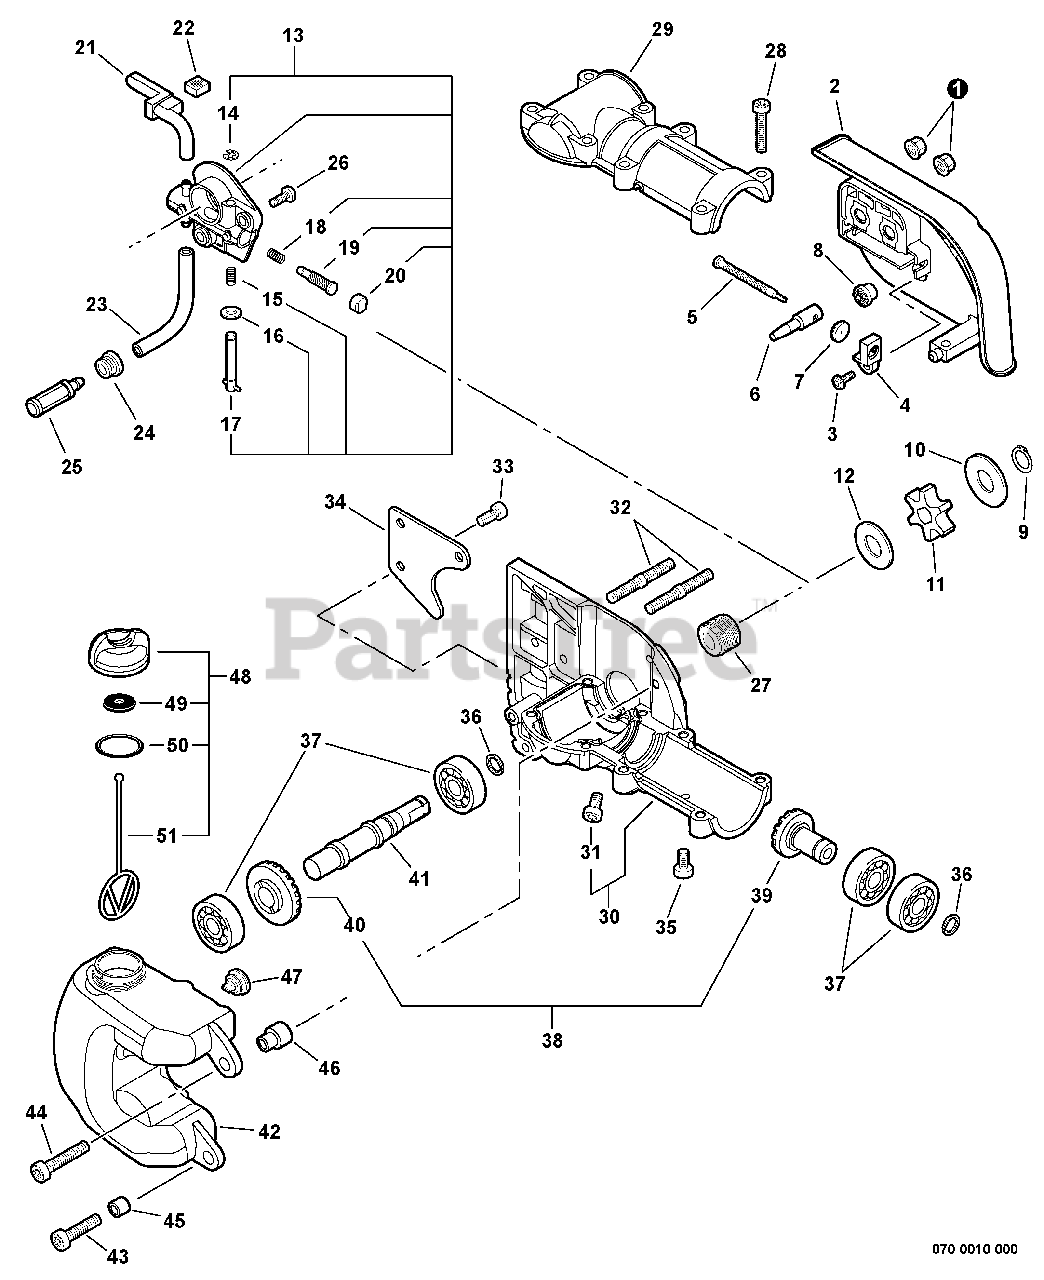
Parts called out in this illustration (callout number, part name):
1	NUT, FLANGE M6
2	GUARD, SPROCKET
3	SCREW 4
4	COLLAR 8
6	TENSIONER, CHAIN
7	GEAR - 14 TOOTH
8	GEAR - 14 TOOTH
9	RING, SNAP
10	WASHER 10
11	SPROCKET, DRIVE
12	WASHER 10.2×24.5×1.2
13	AUTO-OILER ASSY
17	ADJUSTER, OILER
19	PLUNGER ASSY
20	CAP, PLUNGER
21	PIPE, OIL OUTLET
22	PAD, FOAM
23	PIPE, IMPULSE 3×6×75
24	GROMMET
25	FILTER, OIL
26	BOLT, TORX 5×10
27	GEAR, WORM
28	BOLT, TORX 5×25
29	COVER, GEAR CASE
30	CASE, GEAR
31	BOLT, TORX 5×10
32	BOLT, STUD 6
33	SCREW 5×10
35	BOLT M5×10
36	RING, SNAP Ø12
37	BEARING, BALL
38	GEAR SET
39	GEAR, BEVEL
40	GEAR, BEVEL - 23 TOOTH
41	SHAFT, GEAR
42	TANK, OIL
43	BOLT, TORX 5×20
44	BOLT, TORX 5×25
45	SPACER 6.2×7.8×6
46	COLLAR 6
47	VENT ASSY
48	CAP ASSY
49	GASKET, CAP
50	O-RING 18
51	CONNECTOR, CAP L= 60 MM
